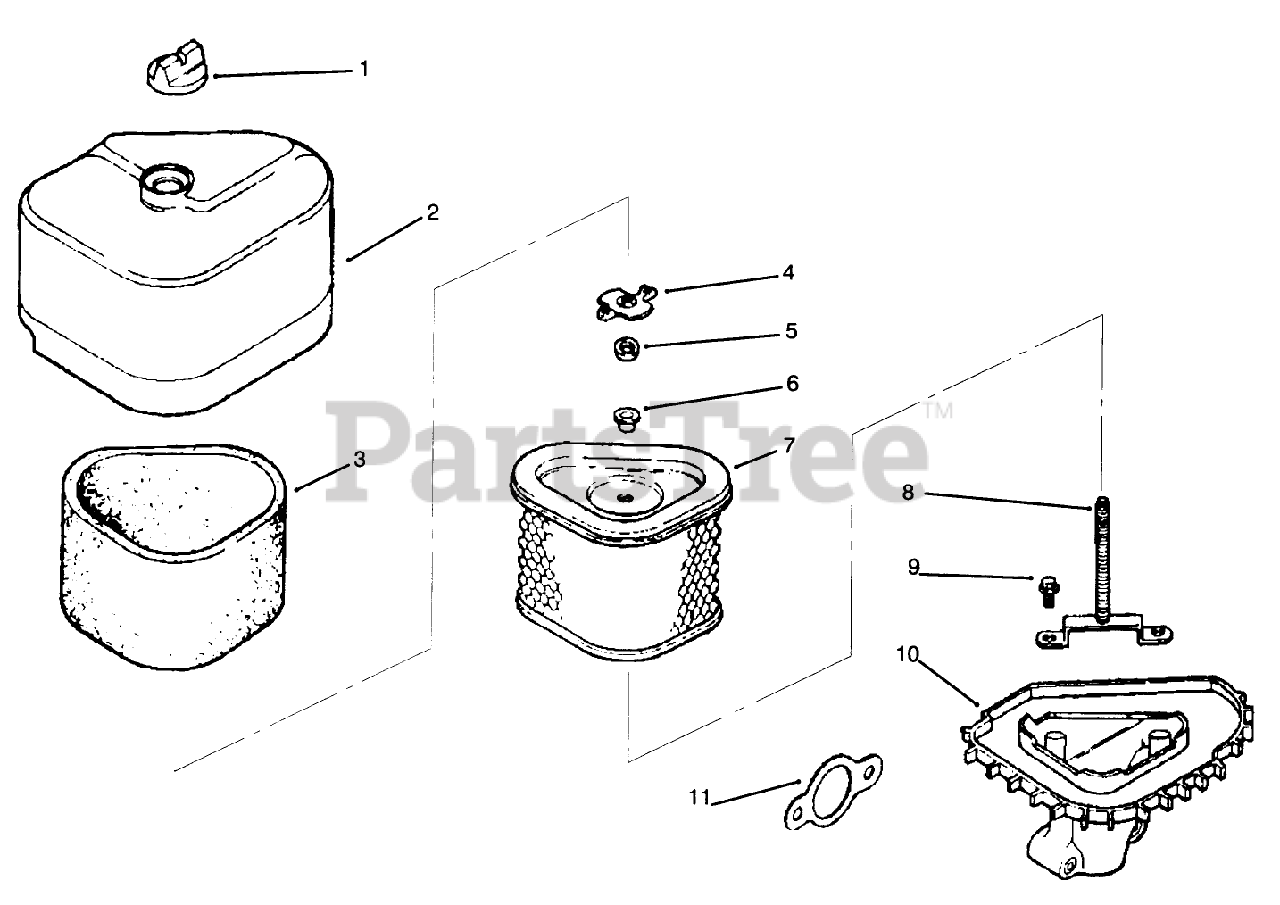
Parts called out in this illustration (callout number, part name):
1	Knob-Cover
2	Cover-Air Cleaner
3	Precleaner-Element
4	Wingnut
5	Washer
6	Grommet
7	Element-Air Cleaner
8	Stud-Mounting Plate
9	Screw
10	Base-Air Cleaner
11	Gasket-Air Cleaner
